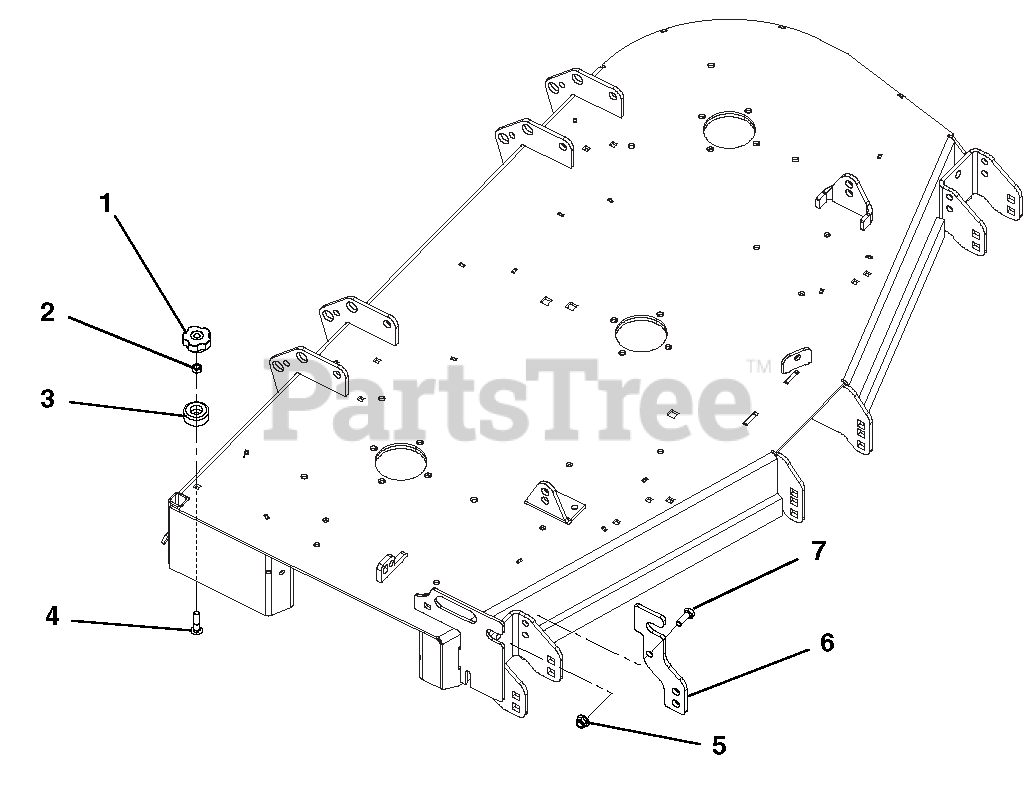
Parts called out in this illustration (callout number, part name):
1	KNOB-CLAMPING, .312-18 NYLOC
2	@NUT-LK-CTR .31-18 YWZC
3	BUMPER,RECESSED1.50X.63 W/.31
4	@BLT-RDHDSQNK .31-18X1.50 G5YZ
5	@NUT-LK-NYL-FLG .38-16 YWZC
6	CHUTE STORAGE BRACKET - RED
7	@BLT-HEX .38-16X1.00 GR5 YWZC
